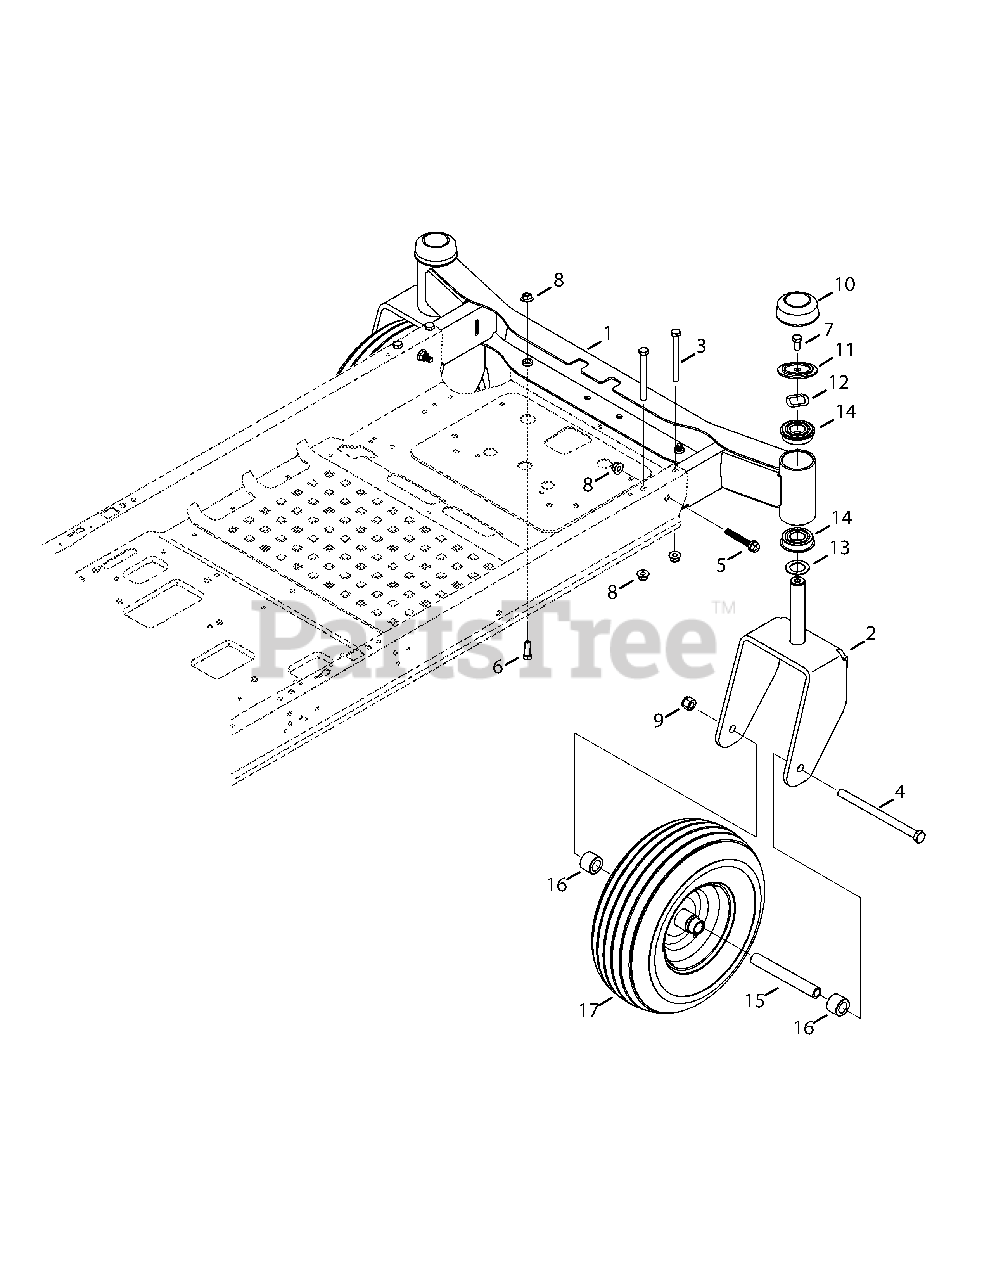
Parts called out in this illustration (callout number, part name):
1	Front Axle
2	Caster Wheel Bracket
3	Hex Cap Screw, 3/8-16 x 3.75
4	Hex Cap Screw, 1/2-20 x 7.25
5	Hex Flange Screw, 3/8-16 x 2.00
6	Hex Cap Screw, 3/8-16 x 1.00
7	Hex Cap Screw, 3/8-16 x .750
8	Flange Lock Nut, 3/8-16
9	Hex Lock Nut, 1/2-20
11	Shoulder Spacer, 2.50 x .200
12	Wave Washer, 1.25 x 1.00 x .300
13	Flat Washer, 1.010 x 1.56 x .060
14	Ball Bearing
15	Spacer, .51 x .75 x 5.825
16	Hub, .76 x 1.23 x .92
17	Wheel Assembly, 13 x 5 x 6
